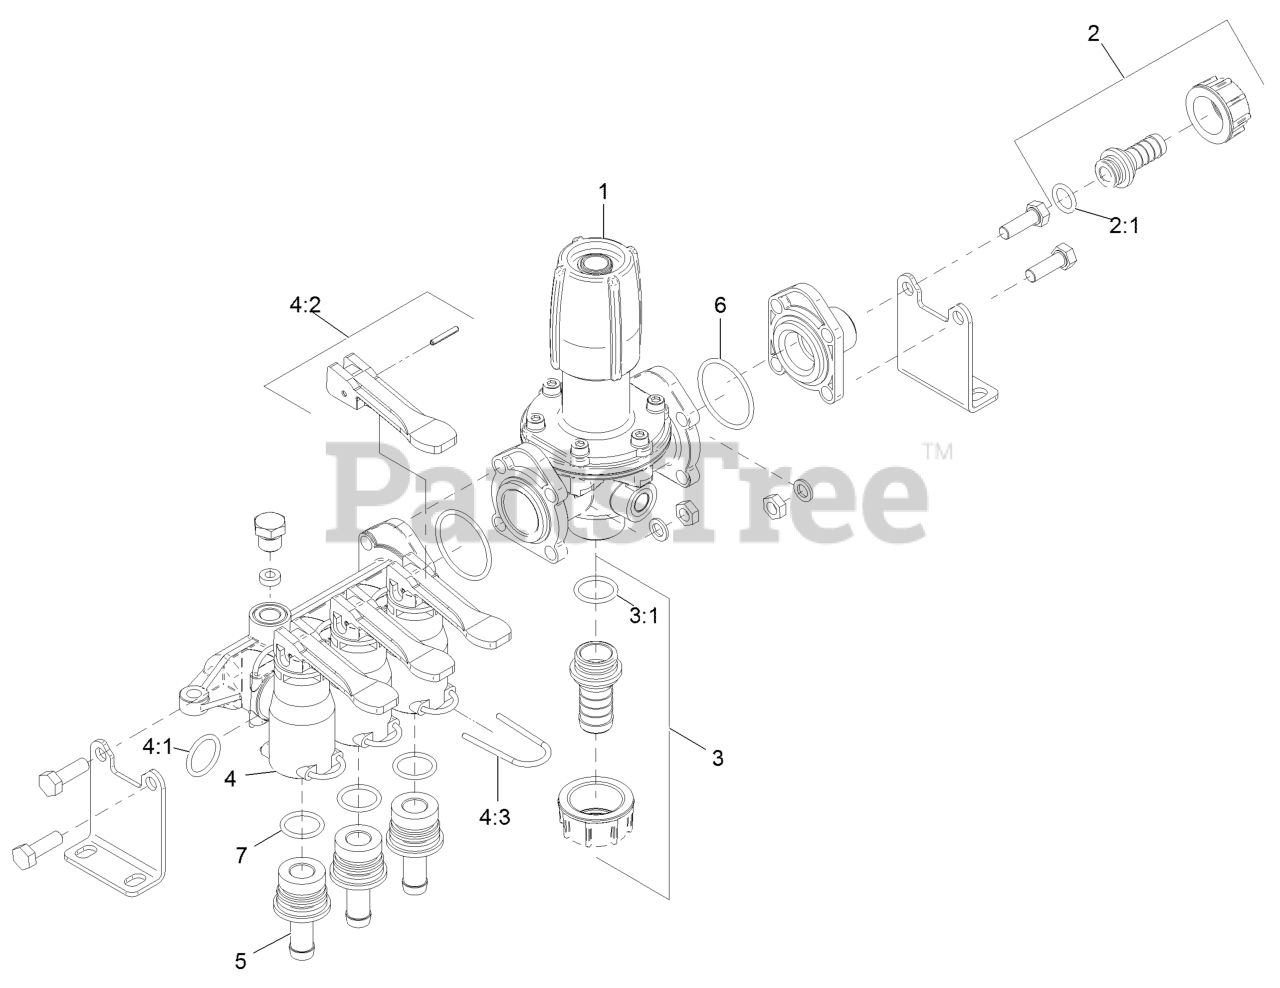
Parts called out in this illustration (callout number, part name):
1	REGULATOR
2	FLYNUT ASSEMBLY
2:1	O-RING KIT, REGULATOR INL
3	FLYNUT ASSEMBLY
3:1	O-RING KIT, REGULATOR OUT
4	VALVE ASSEMBLY W/ O-RING
4:1	O-RING KIT, VALVE INLET
4:2	LEVER AND PIN ASSEMBLY
4:3	WIREFORM RETAINER KIT
5	HOSE BARB
6	O-RING KIT, REGULATOR FLA
7	O-RING KIT, VALVE OUTLET
